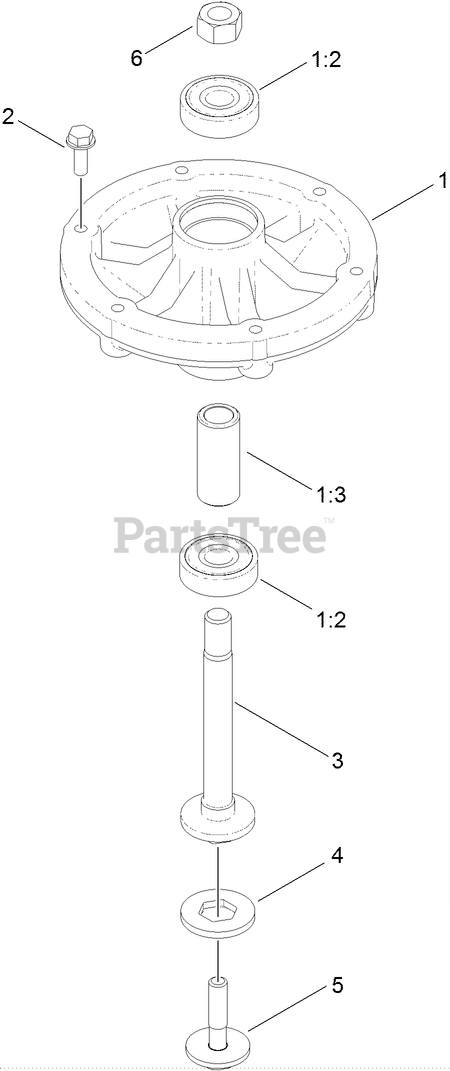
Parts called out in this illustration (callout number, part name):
1	HOUSING-CUTTER
1:2	BEARING
1:3	SPACER-BEARING
2	SCREW-TAPTITE
3	SPINDLE-HEX PILOT
4	WASHER-BLADE DRIVE
5	BOLT-BLADE, SEM
6	NUT-HEX
